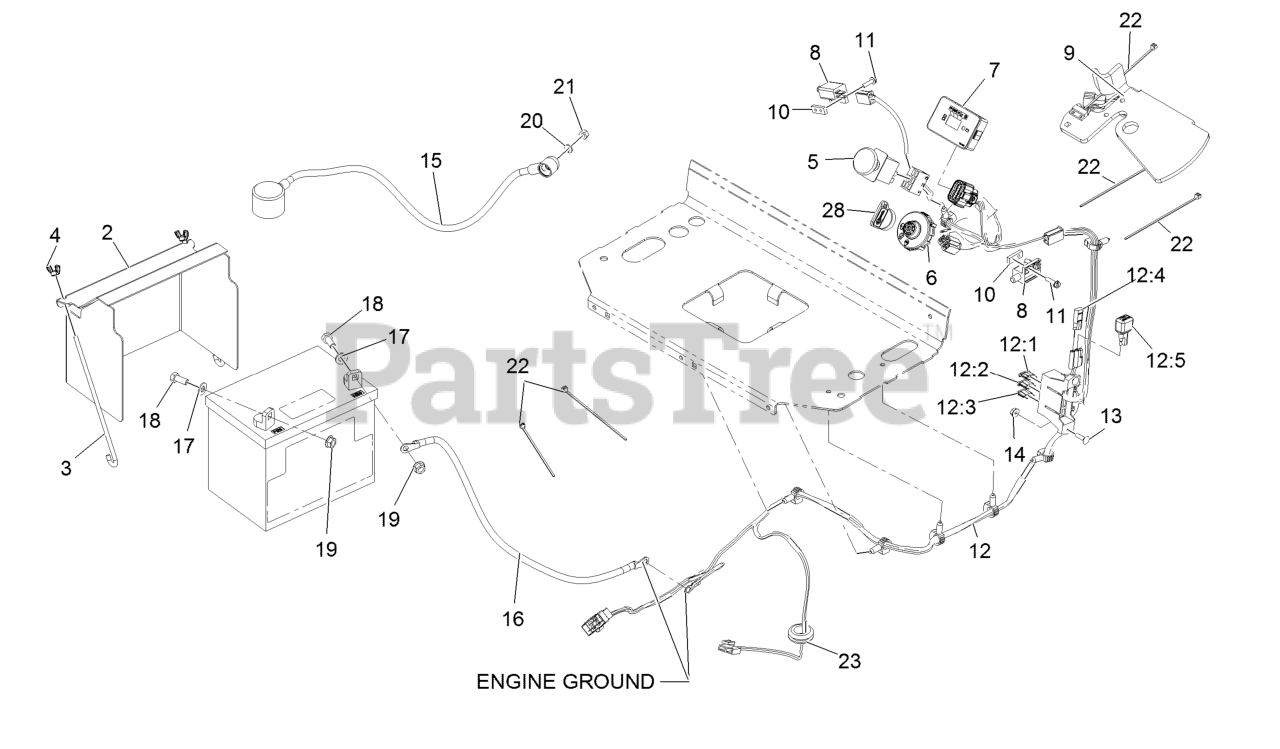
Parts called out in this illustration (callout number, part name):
2	COVER-BATTERY
3	BOLT-HOLDDOWN
4	WINGNUT
5	SWITCH-PTO, ON-ON
7	MODULE-HOUR METER
8	SWITCH-CLOSED, NORMALLY
9	HARNESS-SWITCH, REED
10	PLATE-TAPPED
11	SCREW-HWH
12	HARNESS-WIRE
12:1	FUSE-BLADE, 30 AMP
12:2	FUSE-BLADE, 25 AMP
12:3	FUSE-BLADE, 10 AMP
12:4	CAP-PLUG
13	SCREW-CARR
15	CABLE-BATTERY, POSITIVE
16	CABLE-BATTERY, BLACK
17	WASHER-PLAIN
18	SCREW-HH
19	NUT-HHF, SMOOTH
20	SCREW-HH
21	NUT-HEX
22	TIE-CABLE
23	GROMMET
28	KEY-IGNITION
